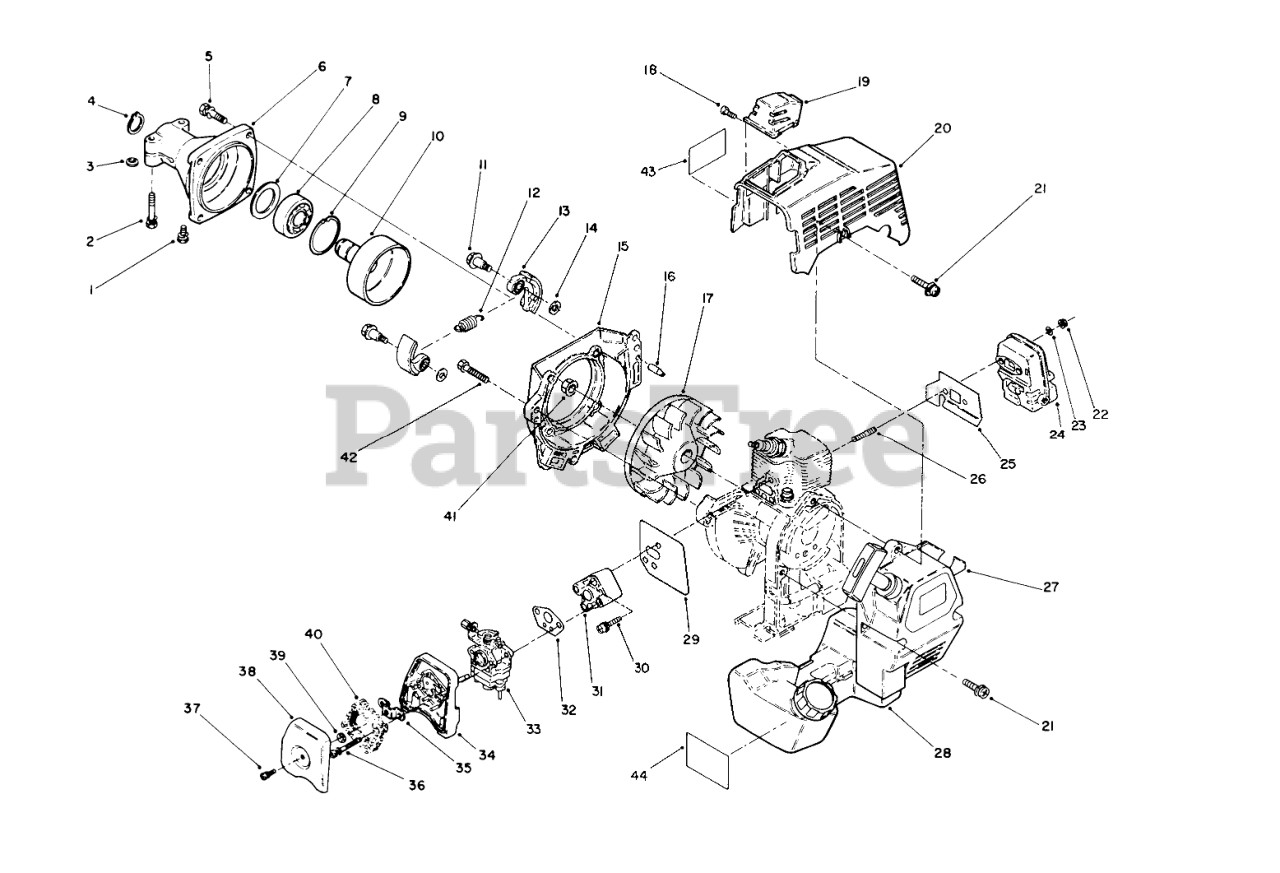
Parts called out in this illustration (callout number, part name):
1	Screw/Washer
2	BOLT-WASHER/ENG
3	WASHER
4	SNAP RING
5	Bolt/Washer
6	CLUTCH CASE
7	Washer
8	BALL BEARING
9	SNAP RING
10	CLUTCH DRUM
11	CLUTCH BOLT
12	Spring
13	SHOE, CLUTCH
14	WASHER
15	Case-Fan
17	Fan
18	SCREW & WASHER
19	SPARK PLUG GUARD
20	TOP COVER
21	SCREW & WASHER
22	MUFFLER FLANGE NUT
23	GASKET
24	MUFFLER ASSEMBLY
25	MUFFLER GASKET
26	MUFFLER STUD
27	Starter-Recoil
28	Tank Assembly-Fuel
29	INSULATOR GASKET
30	SCREW & WASHER
31	INSULATOR
32	CARBURETOR GASKET
33	Carburator Assembly
34	CLEANER CASE
35	BRACKET
36	SCREW W/ WASHER
37	SCREW & WASHERE
38	CLEANER COVER
40	CLEANER ELEMENT
42	BOLT AND WASHER
43	DECAL-SURFACE, HOT
44	DECAL - FUEL TANK
